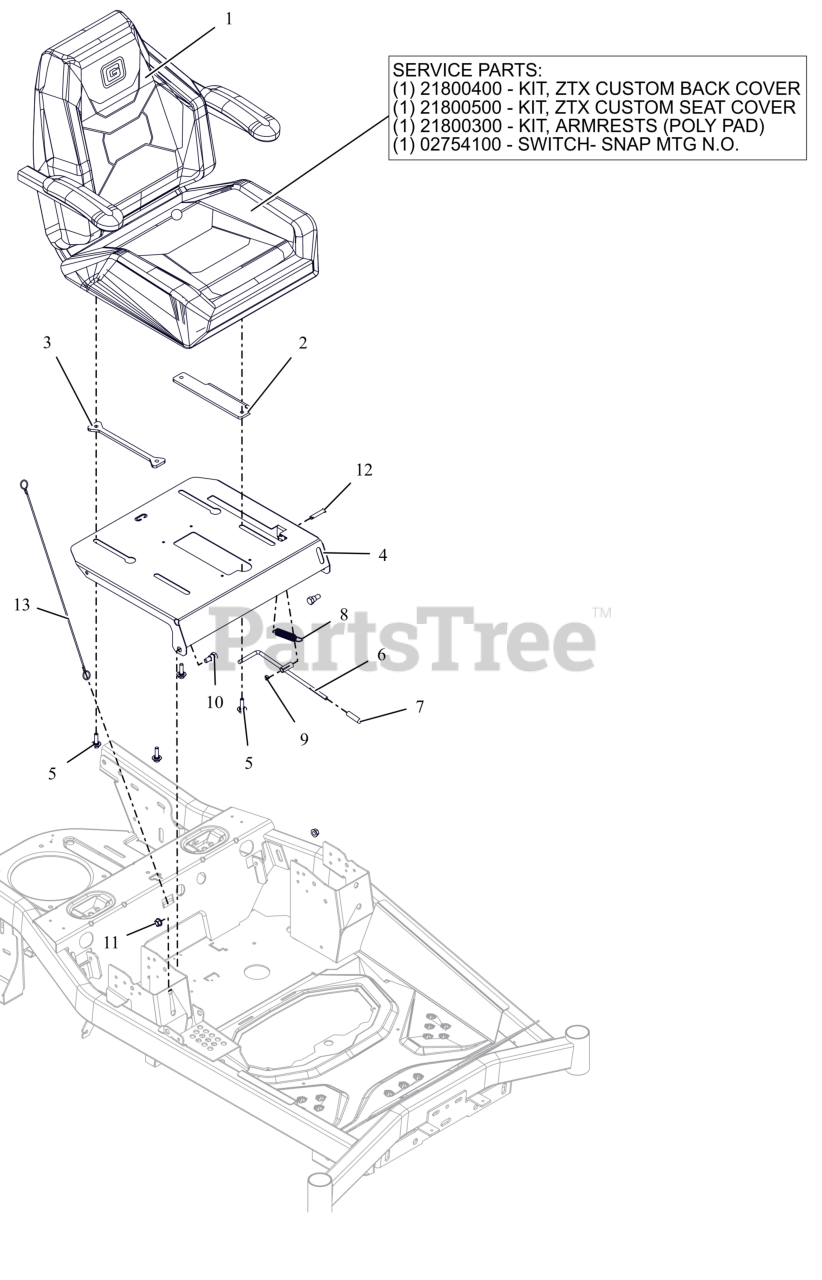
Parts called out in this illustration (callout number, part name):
1	SEAT- ZTX MY23 (WOOD)
1	KIT- ZTX CUSTOM BACK COVER
1	KIT- ZTX CUSTOM SEAT COVER
1	KIT- ARMRESTS ( POLY PAD)
1	SWITCH- SNAP MTG N.O.
2	ADJUSTER-PLATE-SEAT
3	PLATE, ADJ SEAT SLIDE (BLACK)
4	PLATE-SEATE
5	BLT, SHLDR .31-18 X .100
6	WLDMT- LATCH- SEAT
7	GRIP- BLACK .31X1.50
8	SPRG, EXT .653 X .063 X 2.755
9	NUT-PUSH .312
10	BLT-SHLDR .50X.38 ZCC
11	NUT-LK-CTR-FLG .375-16 GF ZCC
12	PIN, CLEV .309X1.75 ZCC
13	LANYARD, SEAT CABLE .093X19.5
